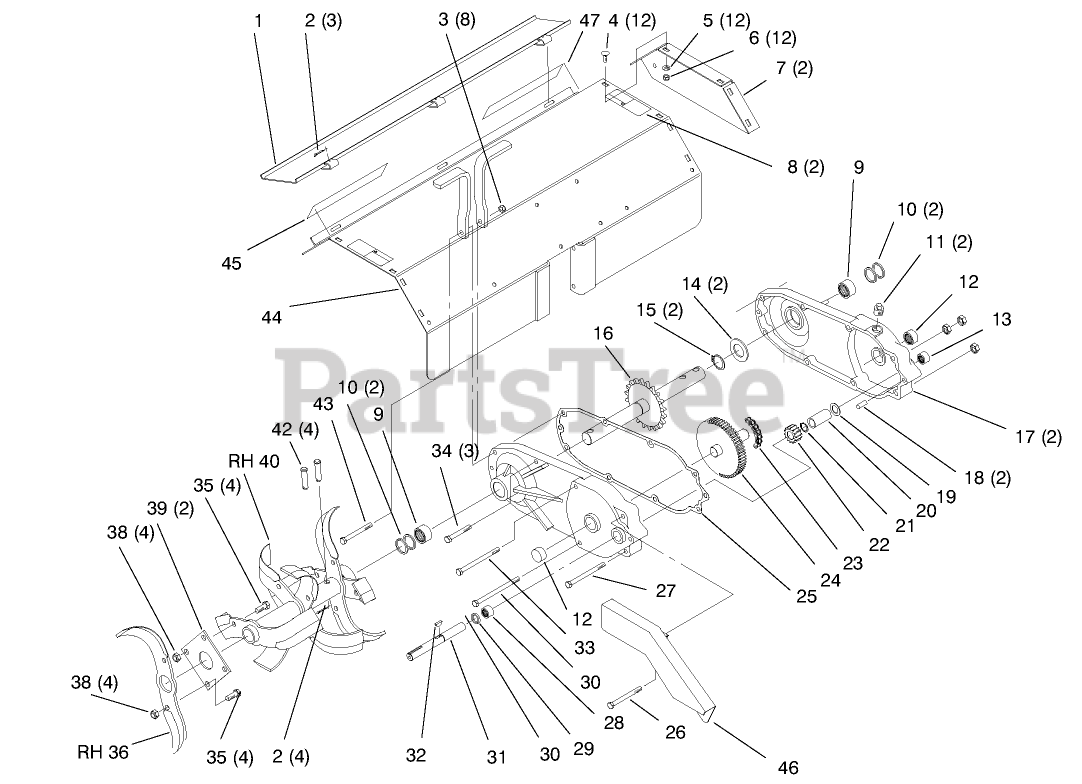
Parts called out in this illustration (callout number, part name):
1	GUARD ASM
2	PIN-COTTER
3	NUT-LOCK, NI
4	BOLT-CARR
5	WASHER-PLAIN
6	NUT-LOCK, NI
7	COVER-TINE END
8	DECAL-DANGER
9	BEARING-NEEDLE
11	PLUG-PIPE, SQH
12	BEARING-NEEDLE
13	BEARING-NEEDLE
14	WASHER
15	RING-RETAINING
16	TINE SHAFT ASM
18	PIN-ROLL
19	WASHER-THRUST
20	TUBE-SPACER
21	RING-SNAP
23	CHAIN
26	SCREW-HH
27	SCREW-HH
28	BEARING-NEEDLE
29	SEAL-OIL
30	SCREW-HH
31	SHAFT-INPUT
32	KEY-WOODRUFF
34	SCREW-HH
35	SCREW-HH
38	NUT-LOCK, NI
39	PLATE-TINE MOUNTING
40	RH TINE ASM
41	LH TINE ASM
42	PIN-CLEVIS
43	SCREW-HH
